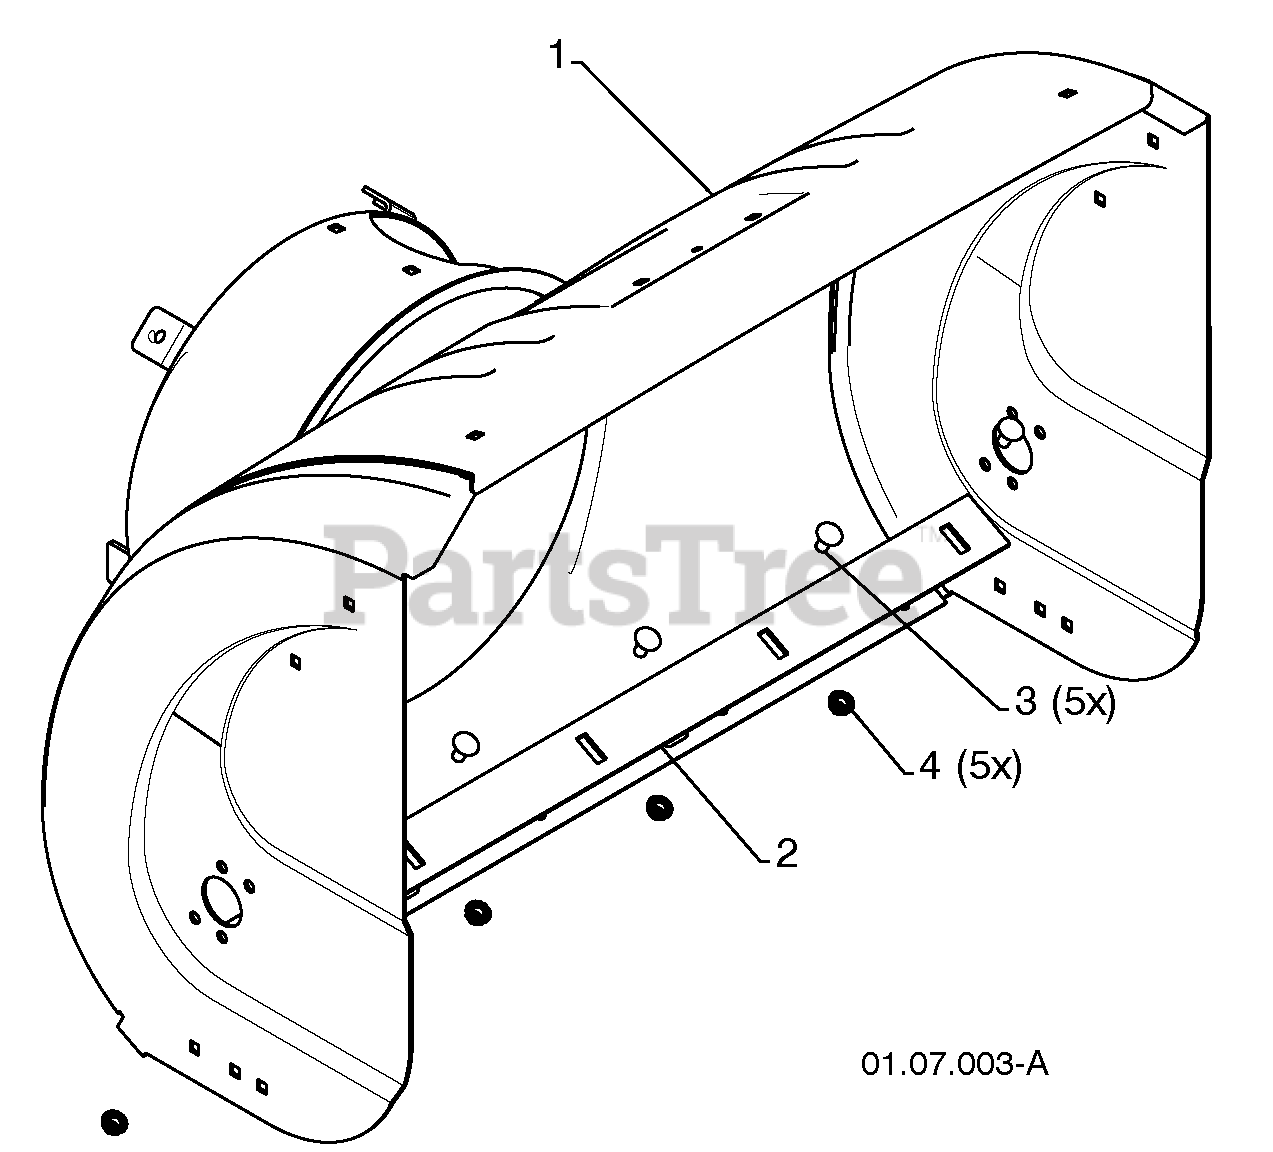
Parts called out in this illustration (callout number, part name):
1	AUGER HOUSING
2	SCRAPPER BAR
3	CARRIAGE BOLT 5/16-18 X .625
4	NUT 5/16-18
